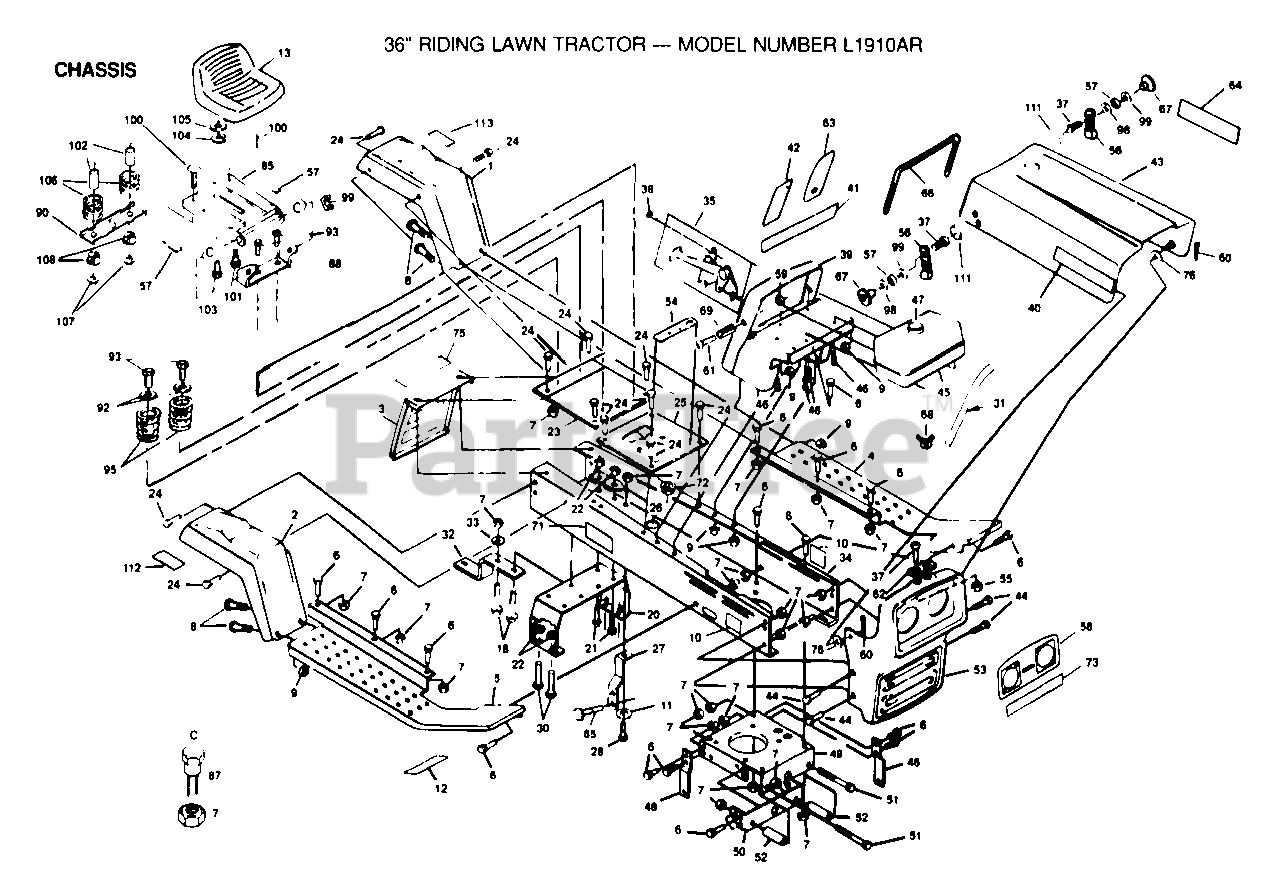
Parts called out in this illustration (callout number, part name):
3	REAR COVER T
6	BOLT
8	BOLT
11	WASHER
18	BOLT
21	BOLT
24	SCREW LT
27	AXLE LT
30	BOLT
37	SCREW
38	SCREW
45	TANK.FUEL.LT
48	BRAKE ROD BRA T
49	ENGINE BASE
50	ROCKER BAR SUPP
52	ROCKER PIVOT LT
56	HOOD LATCH T
57	STRIP FORM
61	SCREW
62	HOOD BUMPER
65	SCREW
67	WELDNUT
69	SPACER LT
76	WASHER M
90	BRKT SWITCH
92	WASHER
93	SCREW GTV
99	WASHER LT
100	BOLT
102	SPACER SPLIT
103	BOLT
104	LOCKWASHER
105	WASHER
106	SPRING
107	NUT T
108	BUSHING
111	SNAP CAP LT
